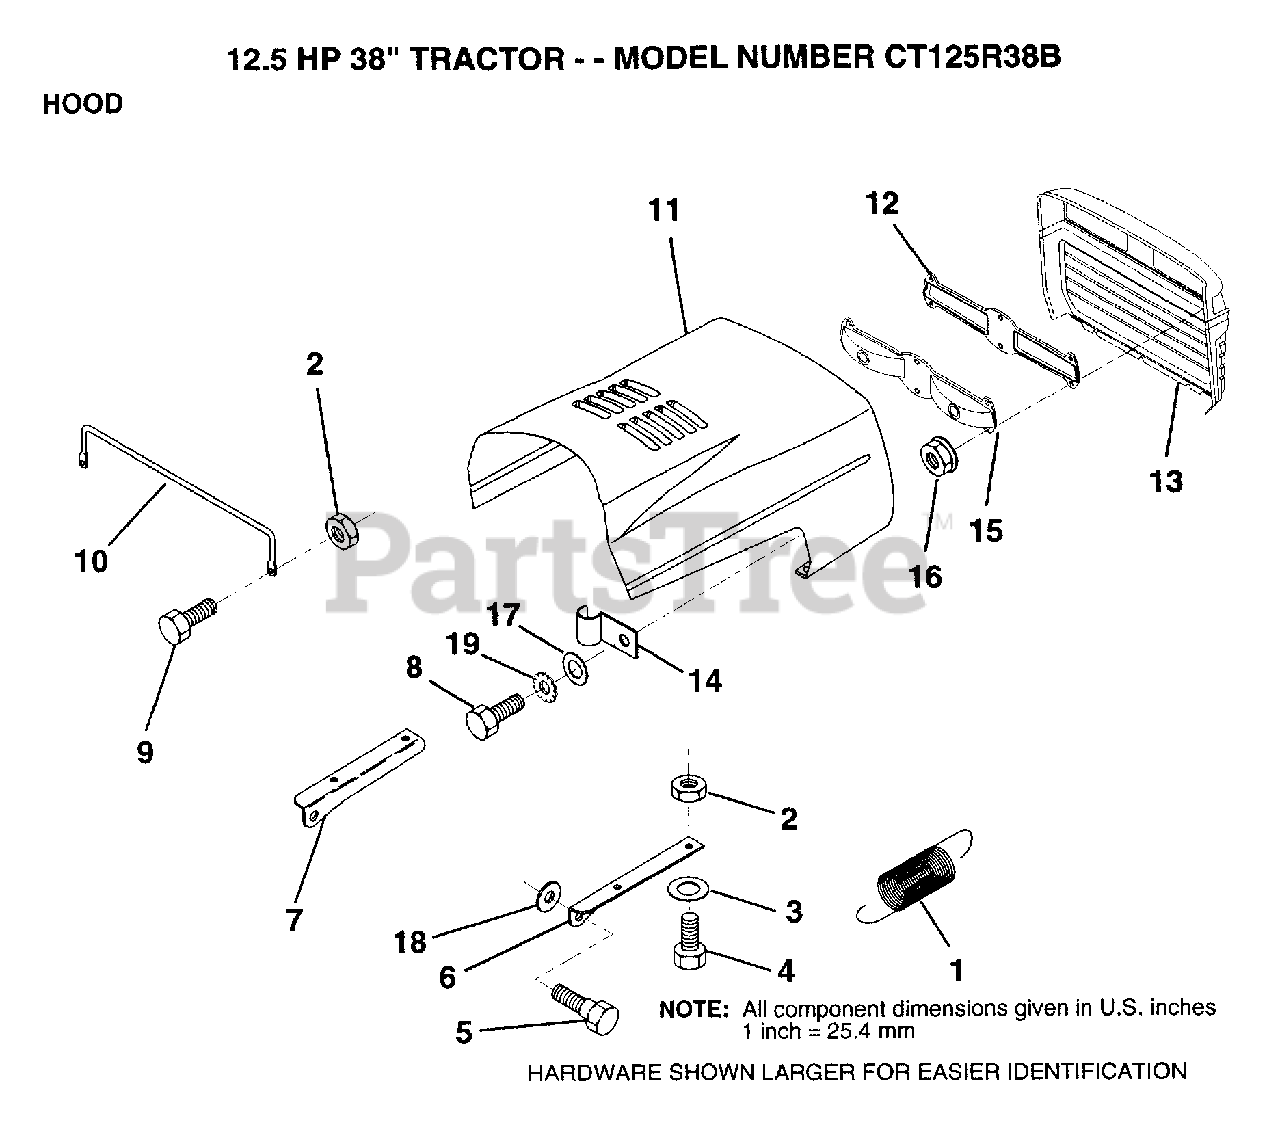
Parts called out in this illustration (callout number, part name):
1	EXT SPRING
2	NUT
3	WASHER
4	BOLT
6	BRKT HOOD RH
7	BRKT HOOD LH
10	"BRACE,HOOD"
14	CLIP T
16	NUT
17	WASHER
18	WASHER
19	LOCKWASHER GT
